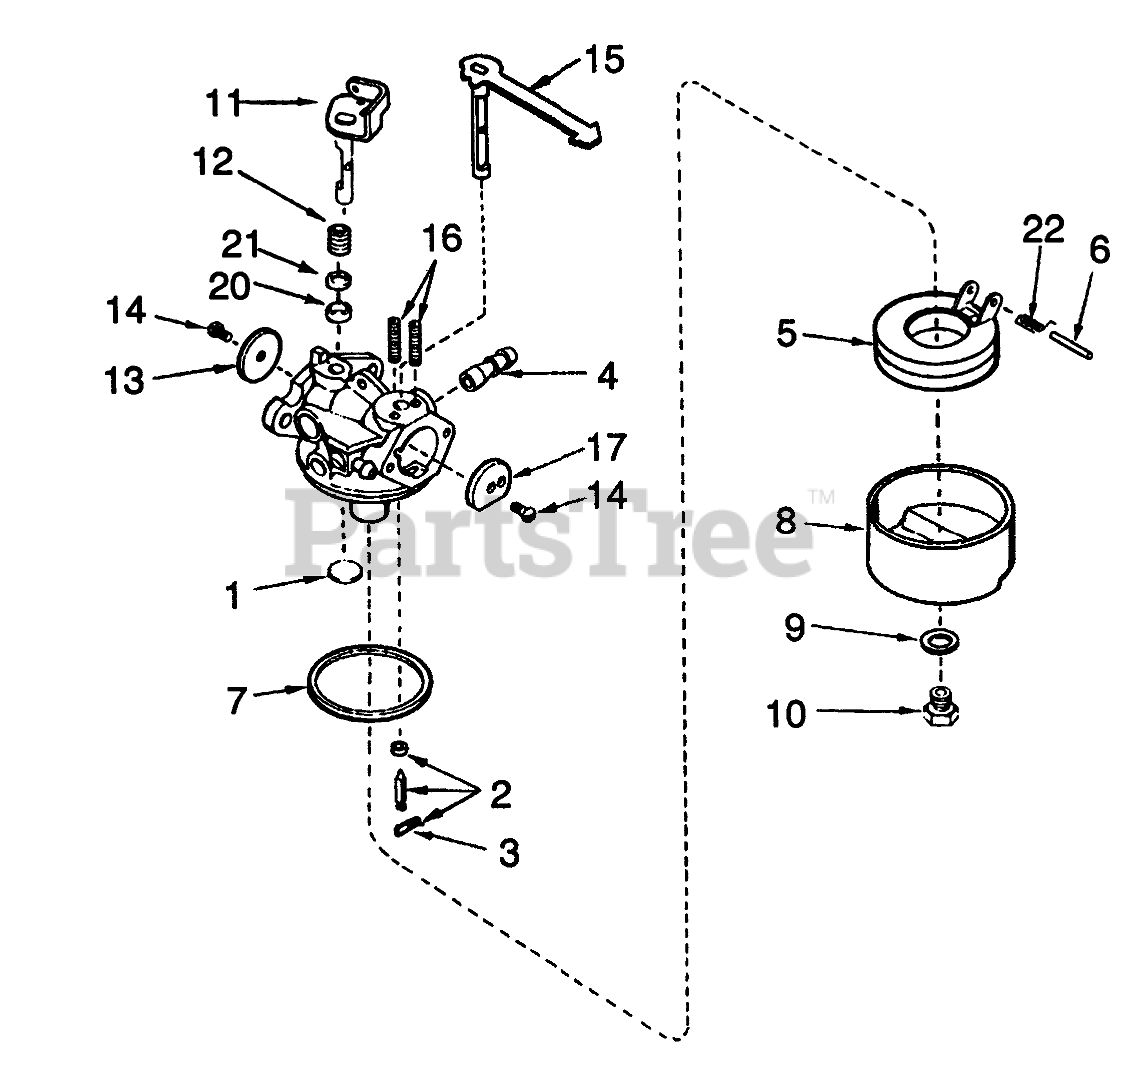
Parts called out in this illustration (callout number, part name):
1	Plug-Welch, Atmospheric Vent
2	Inlet Needle, Seat & Clip (Incl. Ref. #3)
3	Clip-Spring
4	Fitting-Fuel
5	Float
6	Shaft-Float
7	O Ring-Bowl, Float
8	Bowl Float
9	Gasket-Bowl
10	Nut-Float Bowl
11	Shaft/Lever-Throttle
12	Spring-Trottle, Return
13	Shutter-Throttle
14	Screw-Shutter
15	Choke Shaft & Lever Assy.
16	Spring-Positioning, Choke
17	Shutter-choke
20	Seal-Dust
21	Washer-Seal, Dust
22	Spring-Float, Dampening
